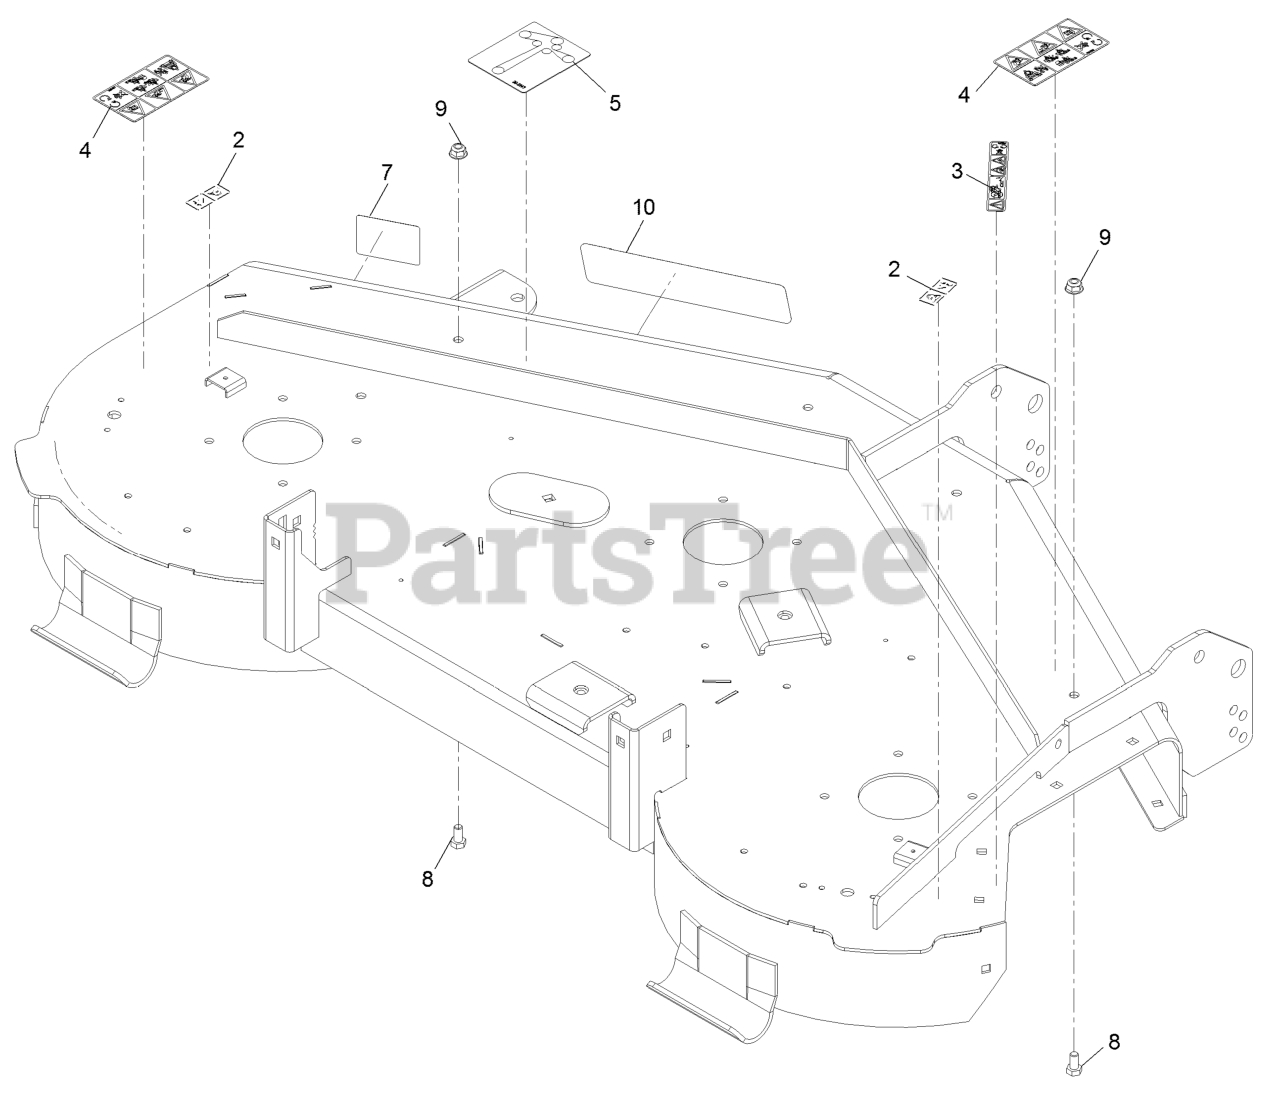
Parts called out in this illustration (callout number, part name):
2	DECAL-DANGER
3	DECAL-DANGER
4	DECAL-DANGER
5	DECAL-ROUTING, BELT
7	DECAL-SCALP, ANTI
8	SCREW-HH
9	NUT-HF, NI
10	DECAL-SERIES 2 - 50
